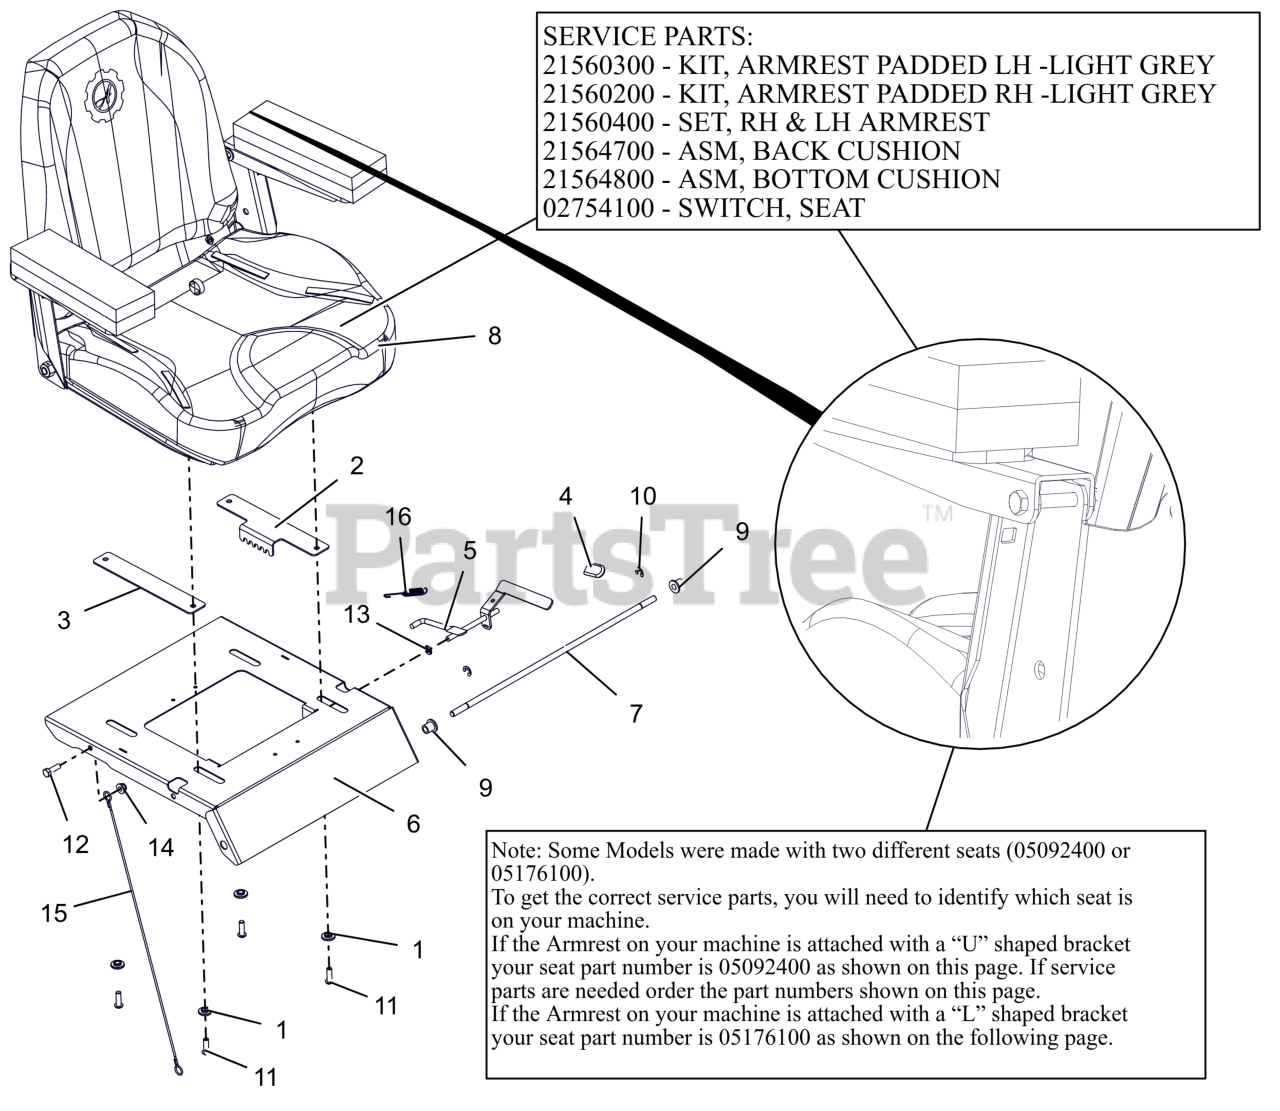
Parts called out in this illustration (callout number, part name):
1	BSHG, FLG .312X.499X.23X.88
2	PLATE, ADJUSTABLE SEAT TRACK
3	PLATE, ADJUSTABLE SEAT SLIDE
4	GRIP, SEAT LEVER, GREY
5	WLDMT, ADJUSTABLE SEAT LATCH
6	PLATE, SEAT
7	ROD, SEAT PIVOT
8	SEAT, IKON XL
8	PAD,LH ARMREST LIGHT GREY SOFT
8	PAD, RH ARMREST LIGHT GREY
8	SET,RH & LH ARMREST -LTGREY
8	ASM, BACK CUSHION-ARIENS X
8	ASM, BOTTOM CUSHION-ARIENS X
8	SWITCH- SNAP MTG N.O.
9	BSHG-FLG .38X.580X.667X.750
10	RG-RTNG-EXT .375X.035 TYP E
11	BLT,SHCS-BTN .31-18X1.00 ZCC
12	BLT,HEX .31-18X1.00 G5 ZCC
13	NUT-PUSH .312
14	NUT,LK-NYL-FLG .31-18 G5ZC120
15	LANYARD, SEAT CABLE .093X19.5
16	SG-TENS .043X.44X3.31 WLD 5.8
